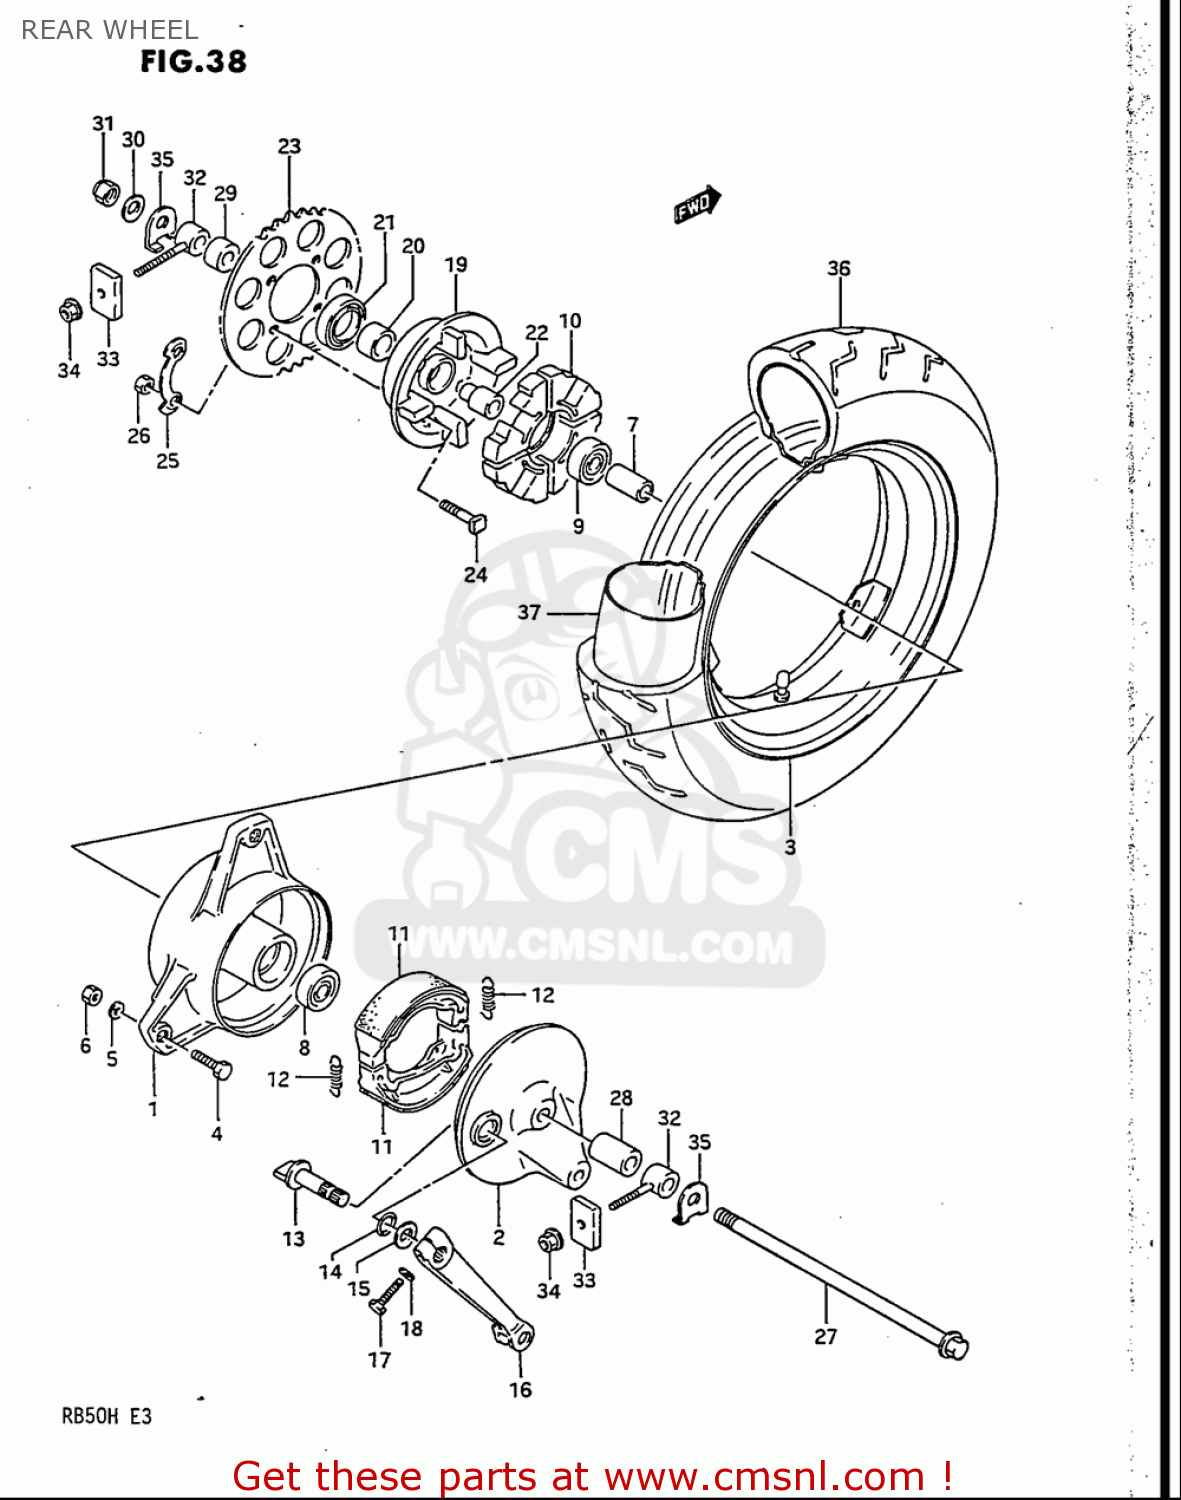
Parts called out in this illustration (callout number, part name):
2	PANEL,REAR HUB
3	WHEEL,RIM(SILVER)
5	WASHER,LOCK
6	NUT
8	BEARING
9	BEARING
10	ABSORBER,RR WHEEL HUB SHOCK
11	SHOE & SPRING SET,BRAKE (NAS)
12	SPRING(L:35.8)
13	CAM,BRAKE
14	O RING(D:2.5,ID:13.8)
15	WASHER(14.5X22X1.6)
17	BOLT
18	WASHER,LOCK
19	DRUM,REAR SPROCKET MOUNT
20	BEARING(17X40X12)
21	SEAL,OIL(25X40X6)
22	RETAINER,RR SPROCKET DRUM
23	SPROCKET,RR(NT:37)
24	BOLT(8X33.5)
25	WASHER
26	NUT
27	AXLE,RR
30	WASHER
31	NUT 12MM
33	PLATE,CHAIN ADJUSTER GUIDE
34	NUT
35	WASHER,CHAIN ADJUSTER
